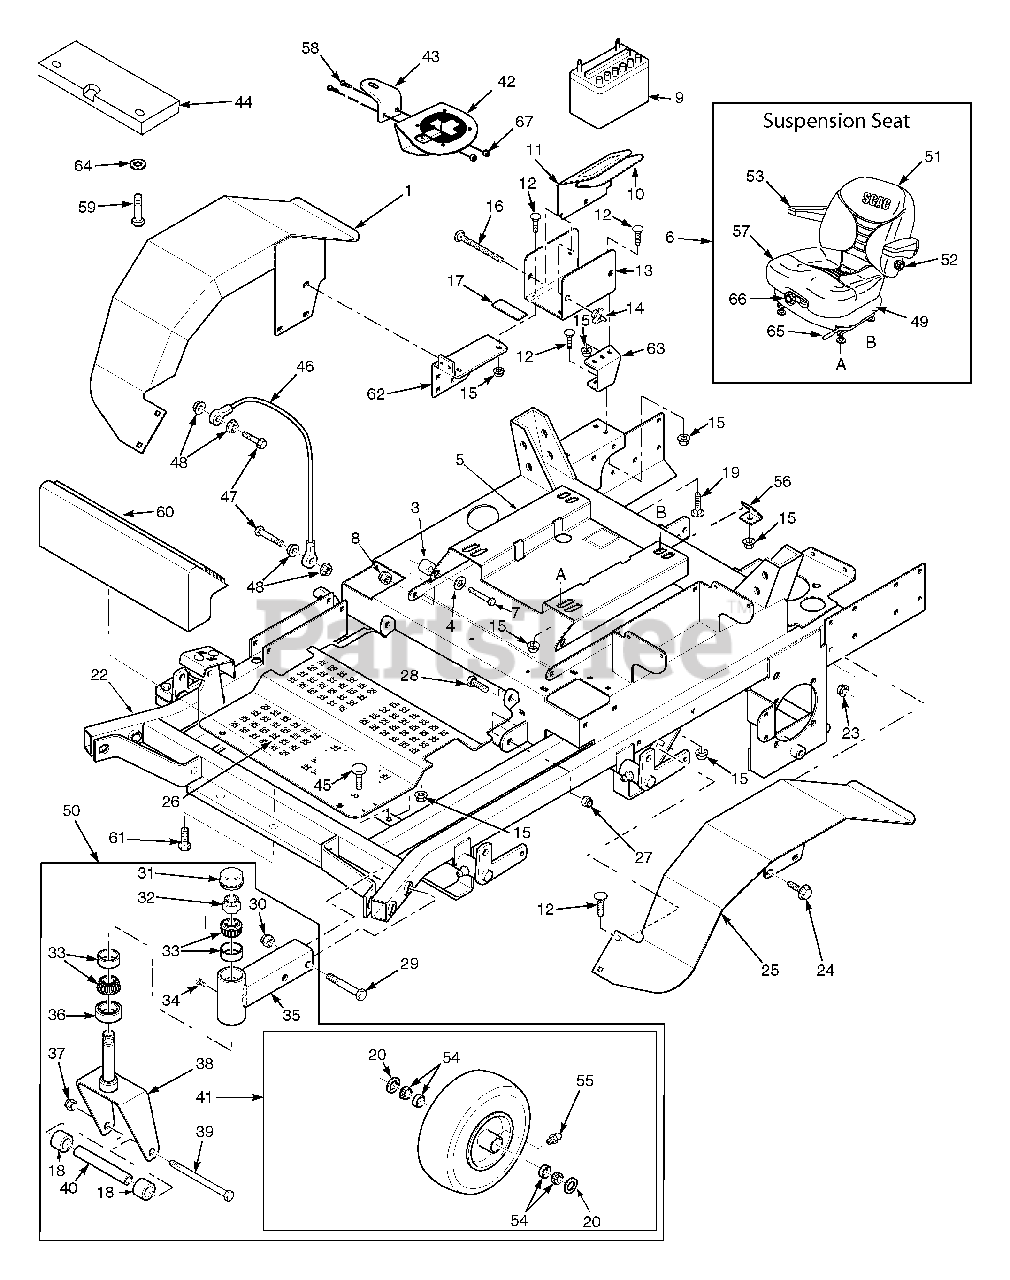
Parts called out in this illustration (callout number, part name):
1	Fender Weldment, RH
2	Bolt, Hex Head, 5/16-18 x 1, Zinc
3	Spacer
4	Flatwasher, 3/8-.391 x .938 x .105
5	Seat Plate
6	Suspension Seat Assembly
7	Bolt, Hex Head 3/8-16 x 2.0"
8	Nut, Elastic Stop 3/8-16
9	Battery
10	Pad, Battery Cover
11	Cover, Battery
12	Bolt, Carriage 5/16-18 x 3/4"
13	Plate, Battery Box
14	Wing Nut, 1/4-20 x 3/4"
15	Nut, Hex Serrated Flange 5/16-18
16	Bolt, Carriage 1/4-20 x 6"
17	Rubber Pad
18	Spacer, Caster Wheel
19	Bolt, Carriage 5/16-18 x 1"
21	Lock Nut, 3/8-16, Elast. Stop
22	Main Frame
23	Nut, Hex Serrated Flange 3/8-16
24	Screw, Hex Serrated Flange 3/8-16 x 1"
25	Fender Weldment, LH
26	Foot Plate
27	Nut, Hex Elastic Stop 3/8-16
28	Bolt, Hex Head 3/8-16 x 1"
29	Bolt, Hex Head 5/8-11 x 4"
30	Nut, Hex Elastic Stop 5/8-11
31	Cap, Grease
32	Nut, Hex Elastic Stop 1.0-14
33	Bearing W/Race
34	Plug, 1/4-28 THD Form
35	Extention Weldment, Caster 61V (LH)
36	Seal, 2.00 OD. x 1.625 Bore
37	Nut, Hex Elastic Stop 1/2-13
38	Yoke Weldment, Caster (61V & 72A)
39	Bolt, Hex Head 1/2-13 x 9-1/2" (61V & 72A)
40	Sleeve, Caster Wheel (61V, 72A)
41	Wheel Assy, 61V, 72A
42	Cup Holder Assembly
43	Mounting Bracket, STT Cup Holder
44	Weight (61" cutter deck only)
45	Bumper, Rubber
46	Cable, Seat Stop
47	Bolt, Hex Head 1/4-20 x 1-1/4"
48	Nut, Hex Serrated Flange 1/4-20
49	Shock Absorber Kit
50	Caster Wheel Assy
51	Back Cushion Kit
52	Lumbar Kit 482948 Knob Kit
53	Armrest Only
54	Bearing w/ Race
55	Grease Fitting
56	Seat Stop
57	Seat Cusion Kit Seat Drain Kit
58	Bolt, Hex Head 1/4-20 x 3/4"
59	Bolt, Hex Head 1/2-13 x 3.5"
60	Footrest
61	Bolt, Hex Head 1/2-13 x 1.5"
62	Mounting Bracket, Battery
63	Support Bracket, Battery Box
64	Flat Washer 1/2-.562 x .1.375 x .109
65	Seat Adjustment, Track Set
66	Weight Adjustment Kit
67	Nut, Elastic Stop 1/4-20
